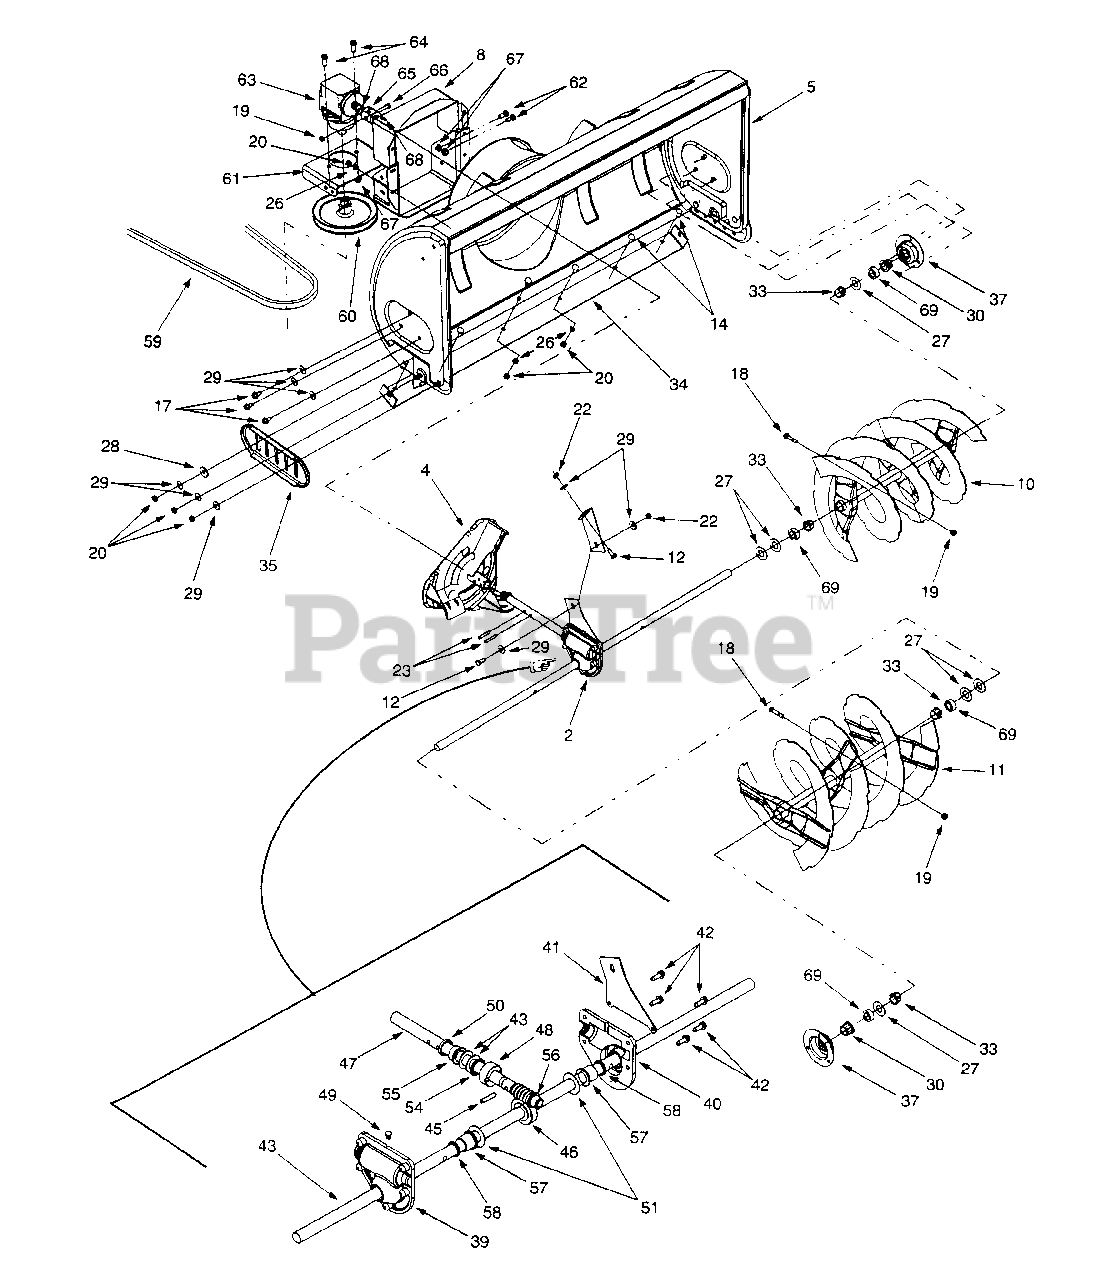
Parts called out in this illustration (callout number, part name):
1	Bearing Housing, 1.85 ID
2	Auger Gear Case
3	Chute Crank Assembly
4	Impeller Assembly, 12"
10	LH Spiral Auger, 40"
11	RH Spiral Auger, 40"
12	Hex Cap Screw, 5/16-24 x .75
13	Carriage Screw, 1/4-20 x .5
14	Carriage Bolt, 5/16-18 x .62
15	Splined Carriage Screw, 5/16-18 x
16	Carriage Bolt, 5/16-18 x .75
17	Self Tapping Screw, 5/16-18 x .625
18	Shear Bolt, 5/16-18 x 1.5
19	Hex Lock Nut,5/16-38
20	Hex Nut, 5/16-18
21	Hex Flange Lock Nut, 1/4-20
22	Hex Nut, 5/16-24
23	Spirol Pin, 1/4 x 1-1/2
24	Spirol Pin, .125 x .812
25	Adapter Chute
26	Lock Washer, 5/16
27	Flat Washer, .76 x 1.49 x .06
28	Flat Washer, .344 x 1.125 x .12
29	Bell Washer, .340 x .872
30	hex Flange Bearing, .75 ID
31	Flange Ball Bearing, .75 x 1.85
32	Plastic Bushing, .38
33	Flange Bushing, .80 x .91
34	Skid Plate Bracket, 42"
35	Slide Shoe
36	Joint Block Assembly
37	Hex Bearing Housing, 1.0
38	Chute Crank Bracket
39	RH Reducer Housing
40	LH Reducer Housing
42	Self Tapping Screw, 1/4-20 x .75
43	Spiral Axle, 41.5"
44	Hi-Pro Key, 3/16 x 5/8
45	Spring Spirol Pin, .25 x 1.25
46	Worm Gear, 20-Tooth
47	Worm Shaft
48	Thrust Collar
49	Grease Plug
50	Grease Seal
51	Flat Washer, .76 x 1.5 x .030
52	Flat Washer, .508 x 1.0 x .020
53	Thrust Washer, .75 x 1.25 x .0615
54	Thrust Bearing, .75 x 1.25 x .078
55	Flange Bearing, .75 x 1.0 x .59
56	Flange Bearing, .503 x .75
57	Flange Bearing, .754 x 1.0 x .925
58	Grease Seal
59	Lower V-belt
60	Drive Pulley, 7"
61	Drive Mounting Bracket
62	Hex Cap Screw, 3/8-16 x.75
63	Right Angle Drive
64	Hex Cap Screw, 3/8-16 x 1.0
65	Coupling
66	Hex Cap Screw, 5/16-18 x 1.75
67	Flange Lock Nut, 3/8-16
68	Square Key, 3/16 x .75
69	Spacer, .75 x .125 x .5
